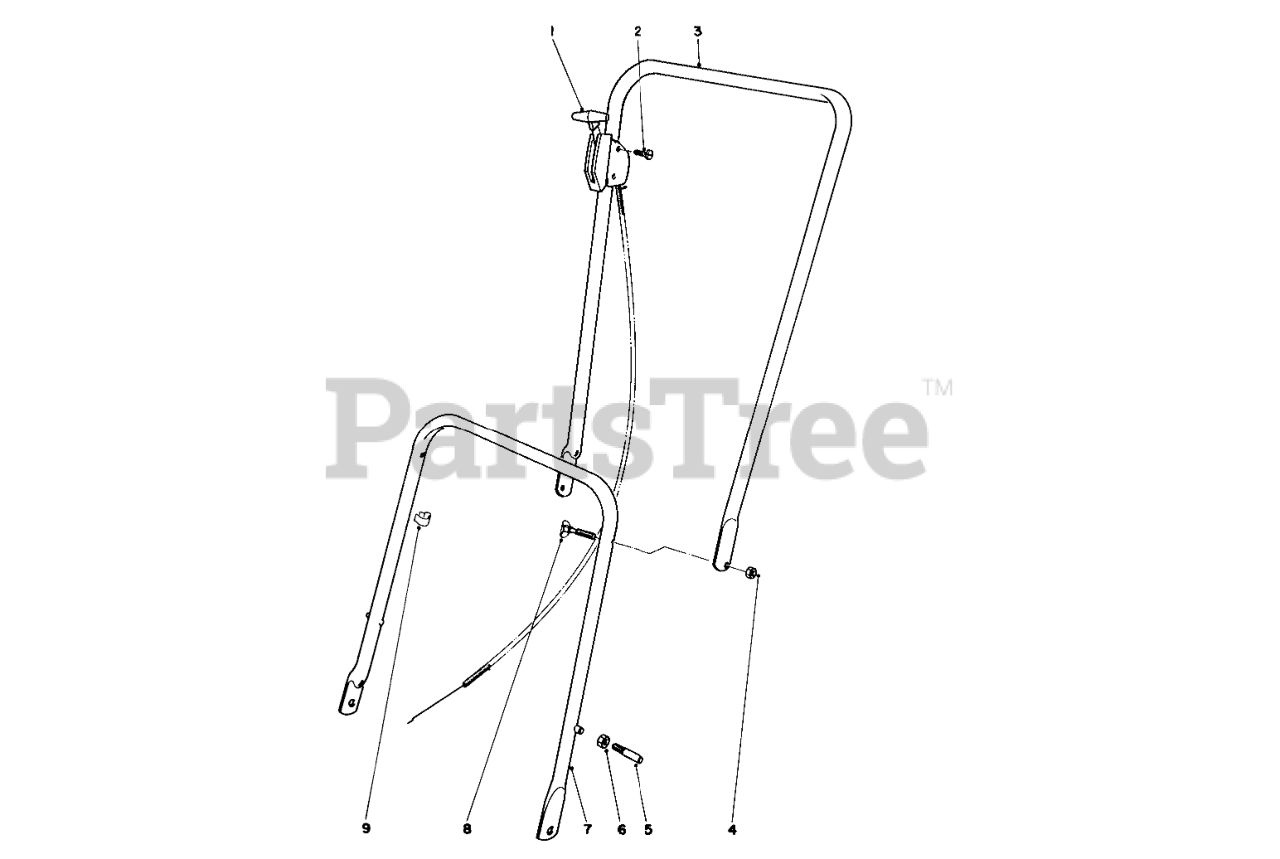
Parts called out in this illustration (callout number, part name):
1	Control-Throttle
2	10-24 X 1 PAN HD SCR
3	Handle-Upper
4	Nut
5	HANDLE PIN
6	Nut
7	LWR HANDLE STAKED ASM
8	1-1/4 LG HANDLE SCREW
9	CONTROL WIRE CLIP
